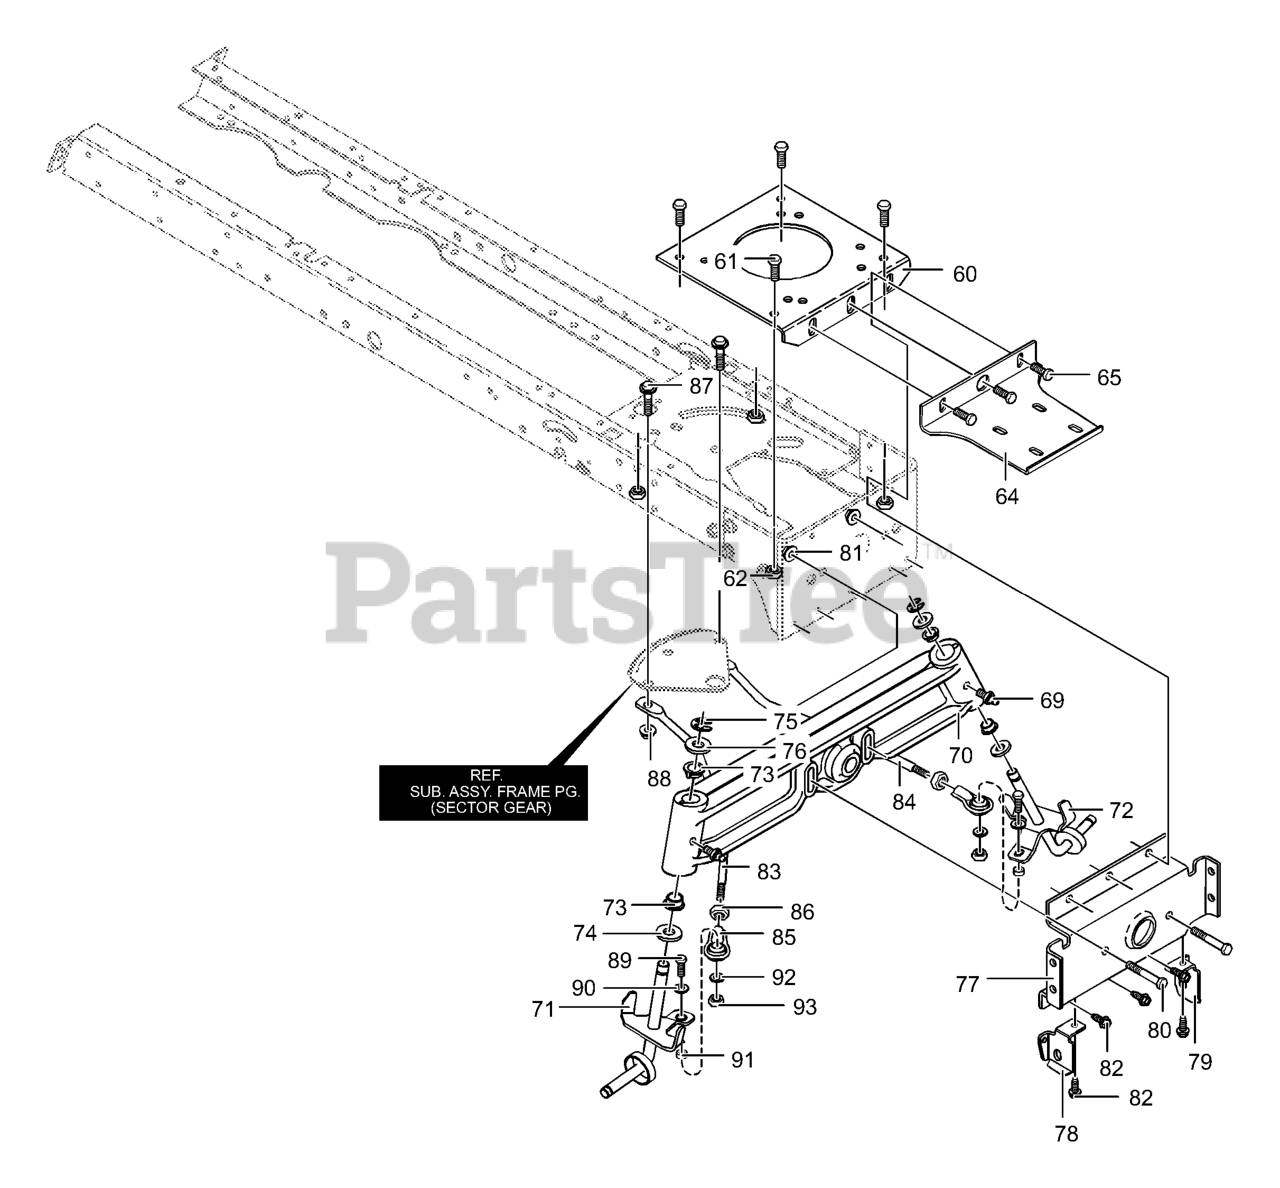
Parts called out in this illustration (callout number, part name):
60	PLATE, ENGINE
61	SCREW 5/16-18X.75
62	NUT, CENTERLOCK
64	BRACKET , MUFFLER
65	SCREW 5/16-18X.75
69	ZERK, GREASE FITTING
70	AXLE, CAST IRON GT
71	SPINDLE, RIGHT
72	SPINDLE, LEFT
73	BEARING, SPINDLE
76	WASHER, FLAT
77	HANGER, AXLE
78	HANGER DECK RH
79	HANGER DECK LH
80	SCREW 5/16-24X2.75
81	NUT, FLANGELOCK
82	SCREW 5/16-18X.75
83	ROD, RIGHT DRAG LINK
84	ROD, LEFT DRAG LINK
85	TIE ROD END
86	NUT, JAM
88	NUT, CENTERLOCK
90	WASHER, FLAT
91	SPACER,
92	WASHER, FLAT
93	NUT, 3/8-16
